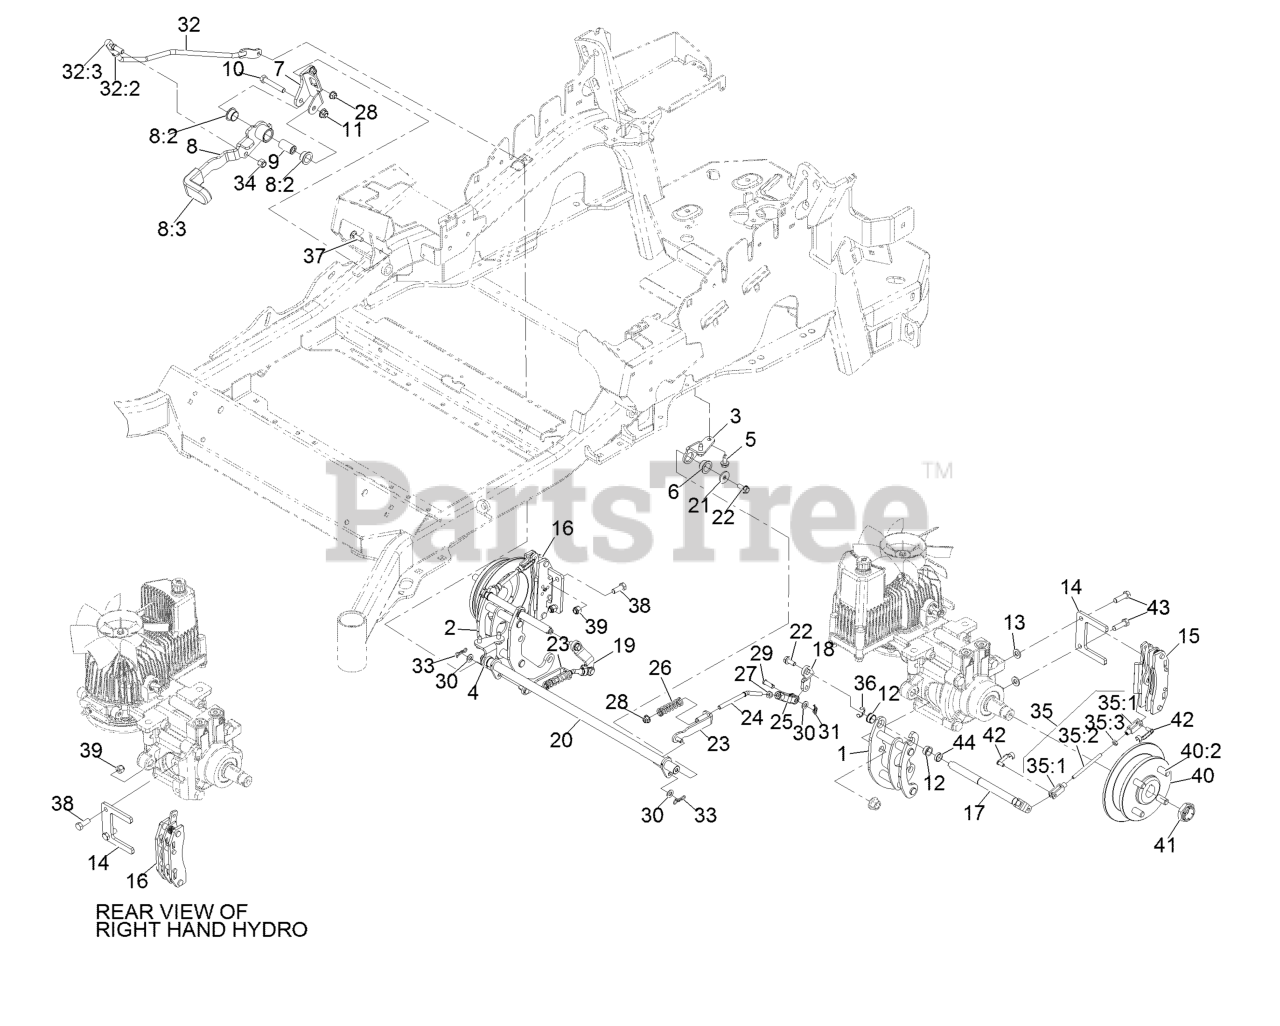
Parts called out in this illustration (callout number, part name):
1	Mount-Bellcrank, LH
2	Mount-Bellcrank, RH
3	Mount-Pivot, LH
4	Mount-Pivot, RH
5	Screw-HWH 5/16-18 X 3/4 Tf
6	Bushing-Flanged
7	Bracket-Mount
8	Brake Lever ASM W/ Grip
8:2	Bushing-Flanged
8:3	Grip-Lever
9	Handle-Pivot, Brake
10	Screw-HH 3/8-16 X 2 1/4
11	Nut-Nyloc 3/8-16 Flg
12	Bushing-Igus
13	Washer-3/8 SAE
14	Plate-Mount, Brake
15	Caliper-Brake
16	Caliper-Brake, RH
17	Bellcrank
18	Arm-Inner, LH
19	Arm-Inner, RH
20	Shaft-Cross
21	Washer-Flat
23	Bracket-L
24	Linkage-Mid
25	Yoke-Offset
26	Spring-Compression
27	Nut-Jam 5/16-24
28	Nut-Nyloc 5/16-18 Flg
29	Pin-Clevis 5/16 X 1 49/64
30	Washer-5/16 SAE
31	Pin-Cotter, Locking
32	Front Linkage ASM
32:2	End-Tie Rod, RH
32:3	Nut-Jam 3/8-24
33	Pin-Cotter, Locking
34	Nut-Nyloc 3/8-24
35	Rear Linkage ASM
35:1	Yoke
35:2	Linkage, Rear
35:3	Nut-Jam 1/4-28
37	Bolt-Carriage 5/16-18 X 1
38	Screw-HH 3/8-16 X 1
39	Nut-Nyloc 3/8-16
40	Wheel Hub ASM
40:2	Stud-Wheel
41	Locknut
42	Pin-Clevis, Spring
43	Screw-HH 3/8-16 X 1 1/4 Patch Lock
